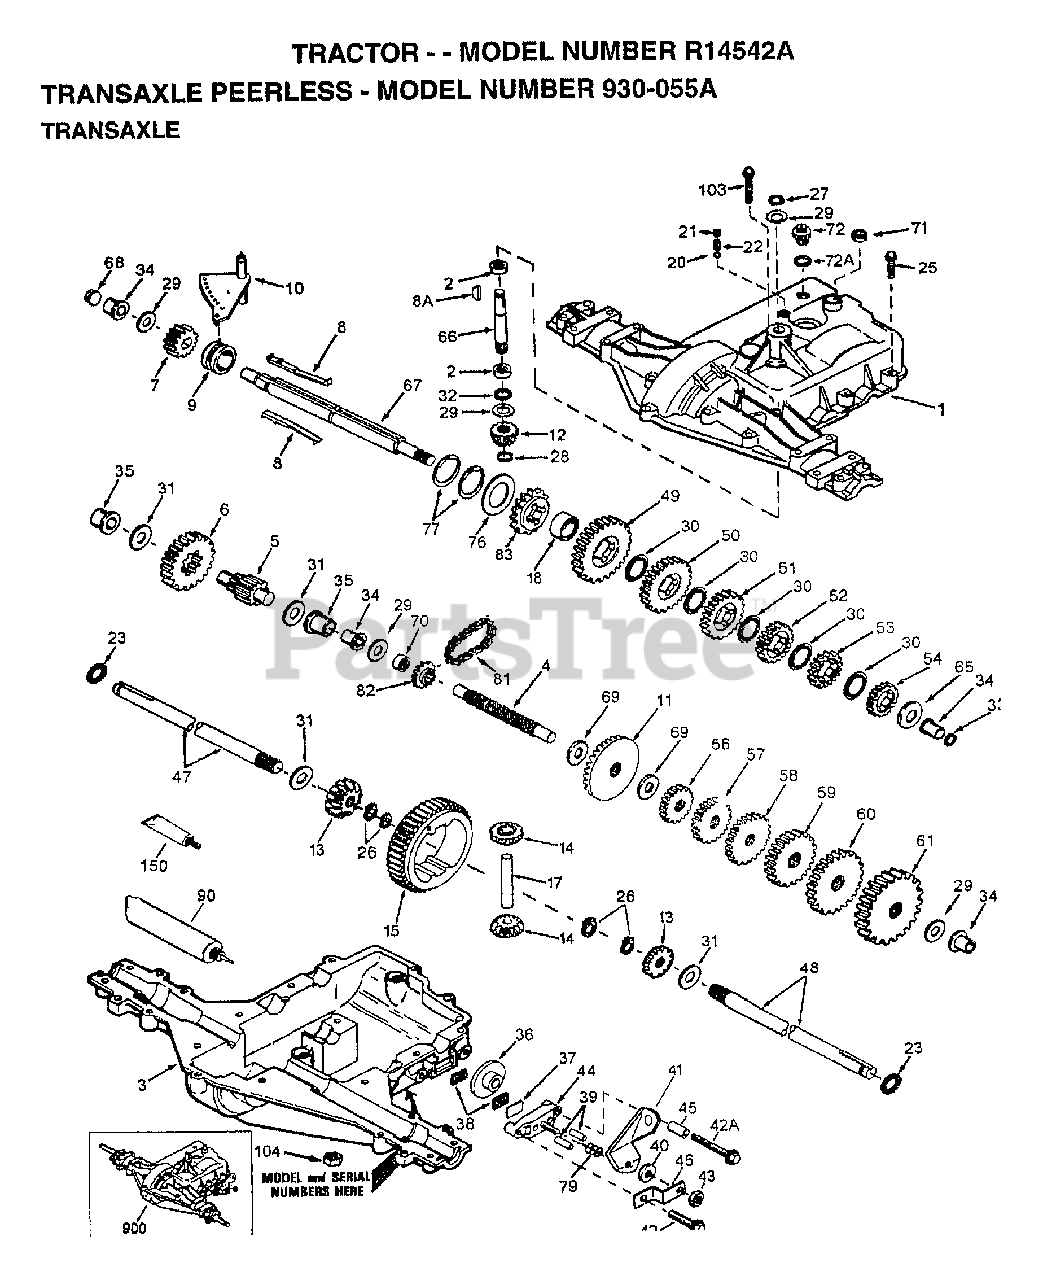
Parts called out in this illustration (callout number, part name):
1	TRANSAXLE COVER
2	BEARING, NEEDLE
3	TRANSAXLE CASE
4	SHAFT, COUNTER
5	OUTPUT SHAFT AND PINION
6	GEAR, OUTPUT
7	GEAR, SPUR, 15 TEETH
8A	KEY, WOODRUFF
9	COLLAR, SHIFTER
10	ROD & FORK ASSY, SHIFT
11	GEAR, BEVEL, 42 TEETH
12	BEVEL PINION, INPUT
13	GEAR, BEVEL
14	GEAR, BEVEL, PINION
17	SPACER, NEUTRAL
20	BALL STEEL, 5/16" DIA.
21	SCREW, 3/8-16 X 3/8"
25	SCREW, 1/4-20 X 1-1/4
26	RING RETAINER
27	RING, RETAINER
28	RETAINING RING
29	WASHER THRUST
30	WASHER THRUST
33	SEAL, SQUARE CUT
34	BUSHING, FLANGED
35	BUSHING, FLANGED
36	DISK, BRAKE
37	PLATE BRAKE PAD
41	BRAKE LEVER
42	SCREW, 1/4-20 X 1-1/4
42A	SCREW, 1/4-20 X 2-1/4
43	LOCKNUT 5/16-24
44	HOLDER BRAKE PAD
46	BRKT BRAKE LEVER
49	GEAR, SPUR, 37 TEETH
50	GEAR, SPUR, 35 TEETH
51	GEAR, SPUR, 30 TEETH
52	GEAR, SPUR, 25 TEETH
53	GEAR, SPUR, 22 TEETH
54	GEAR, SPUR, 19T
56	GEAR, SPUR, 12 TEETH
57	GEAR, SPUR, 15 TEETH
58	GEAR, SPUR, 20 TEETH
59	GEAR, SPUR, 25 TEETH
60	GEAR, SPUR, 28 TEETH
61	GEAR, SPUR, 31 TEETH
65	WASHER, THRUST
66	SHAFT, INPUT
67	SHAFT, BRAKE, 4 KEYED
69	WASHER THRUST
71	SEAL SQUARE CUT
72	THREADED PLUG 9/16-18
76	WASHER, THRUST
77	INVERTED RETAINING RING
81	CHAIN, ROLLER
82	SPROCKET 9T
83	SPROCKET 18T (REV)
90	GREASE BENTONITE, 32 OZ.
150	GASKET ELIMINATOR
900	REPLACEMENT TRANSAXLE
